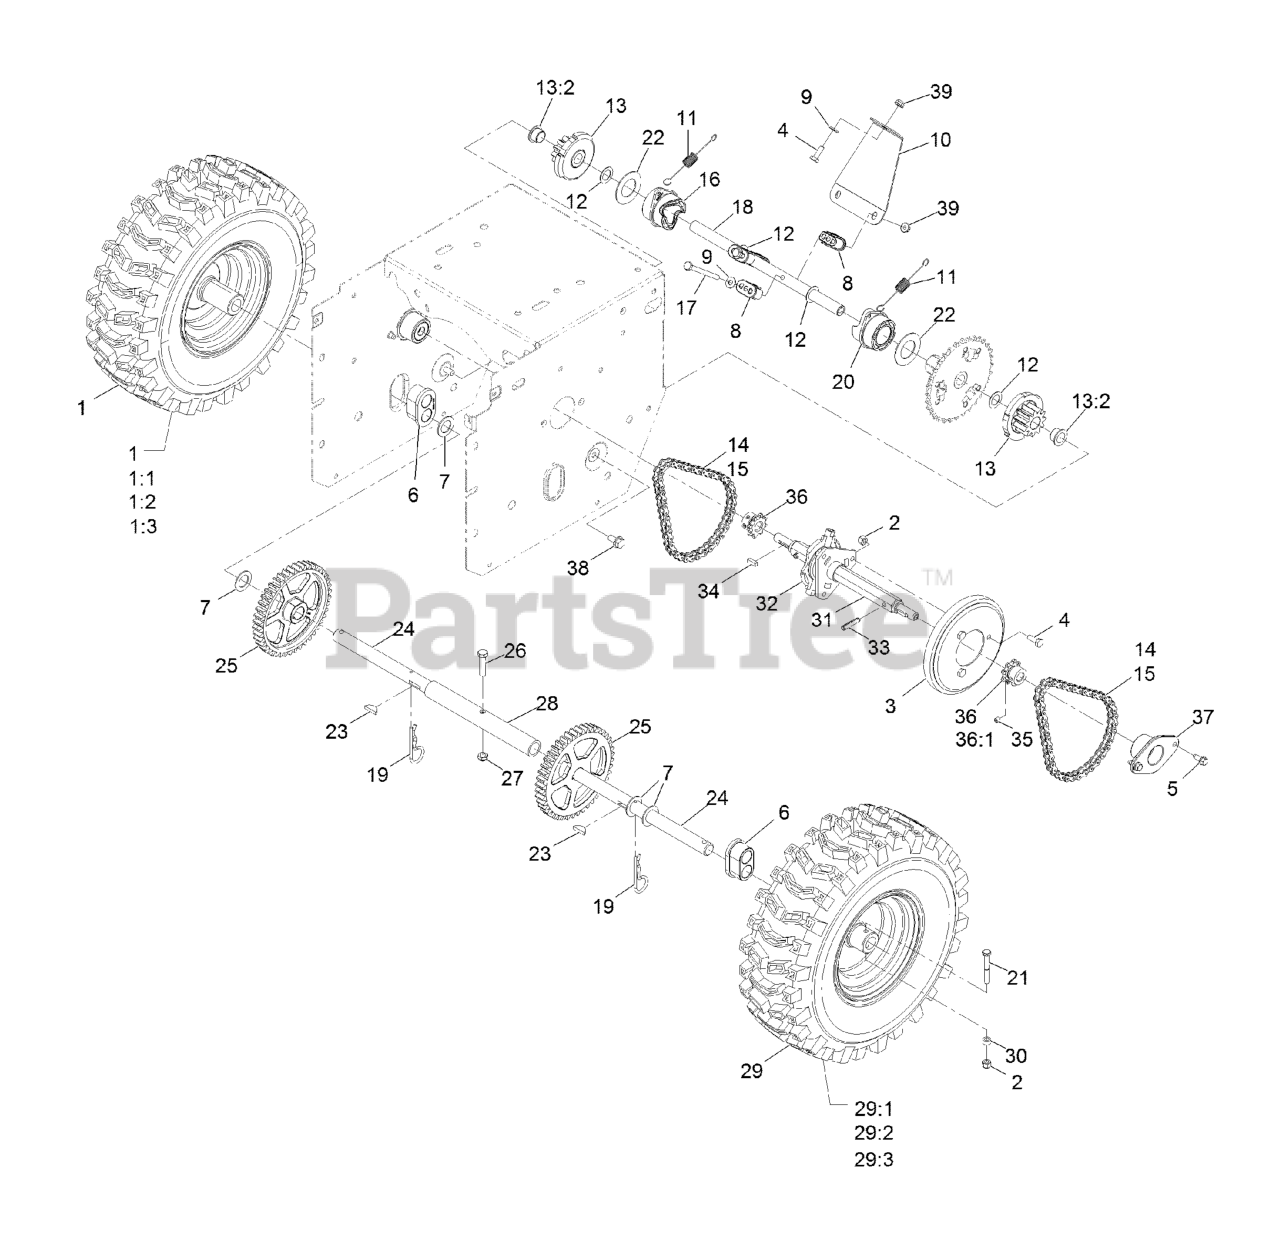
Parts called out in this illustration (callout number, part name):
1	RH Wheel And Tire ASM
1:2	RIM-TIRE
1:3	Stem-Valve
2	NUT-LOCK, NI
3	WHEEL-FRICTION
4	SCREW-HH
5	SCREW-HWH
6	BEARING-AXLE
7	WASHER-THRUST
8	GUIDE-COLLAR
9	WASHER-FLAT
10	BRACE-COLLAR, SHIFT
11	SPRING-EXTENSION
12	WASHER-FLAT
13	11T GEAR ASM
13:2	BUSHING-FLANGE
14	CHAIN-ROLLER
15	LINK-CONNECTING
16	COLLAR-SHIFT, RH
17	SCREW-HH
18	SHAFT-INTERMEDIATE
19	PIN-HAIR
20	COLLAR-SHIFT, LH
21	SCREW-HH
22	WASHER-THRUST
23	KEY-WOODRUFF
24	SHAFT-AXLE
25	GEAR-AXLE, 44 TOOTH
26	SCREW-HH
27	NUT-LOCK, NI
28	TUBE-AXLE
29	LH Wheel And Tire ASM
29:2	RIM-TIRE
29:3	Stem-Valve
30	SPACER-BLADE, ROTOR
31	SHAFT-HEX
32	TRUNNION-HEX
33	PIN-ROLL, SLOTTED
34	KEY-SQUARE
35	SCREW-HSH
36	SPROCKET-8 TOOTH
36:1	SCREW-HSH
37	RETAINER-BEARING
38	SCREW-HWHTF
